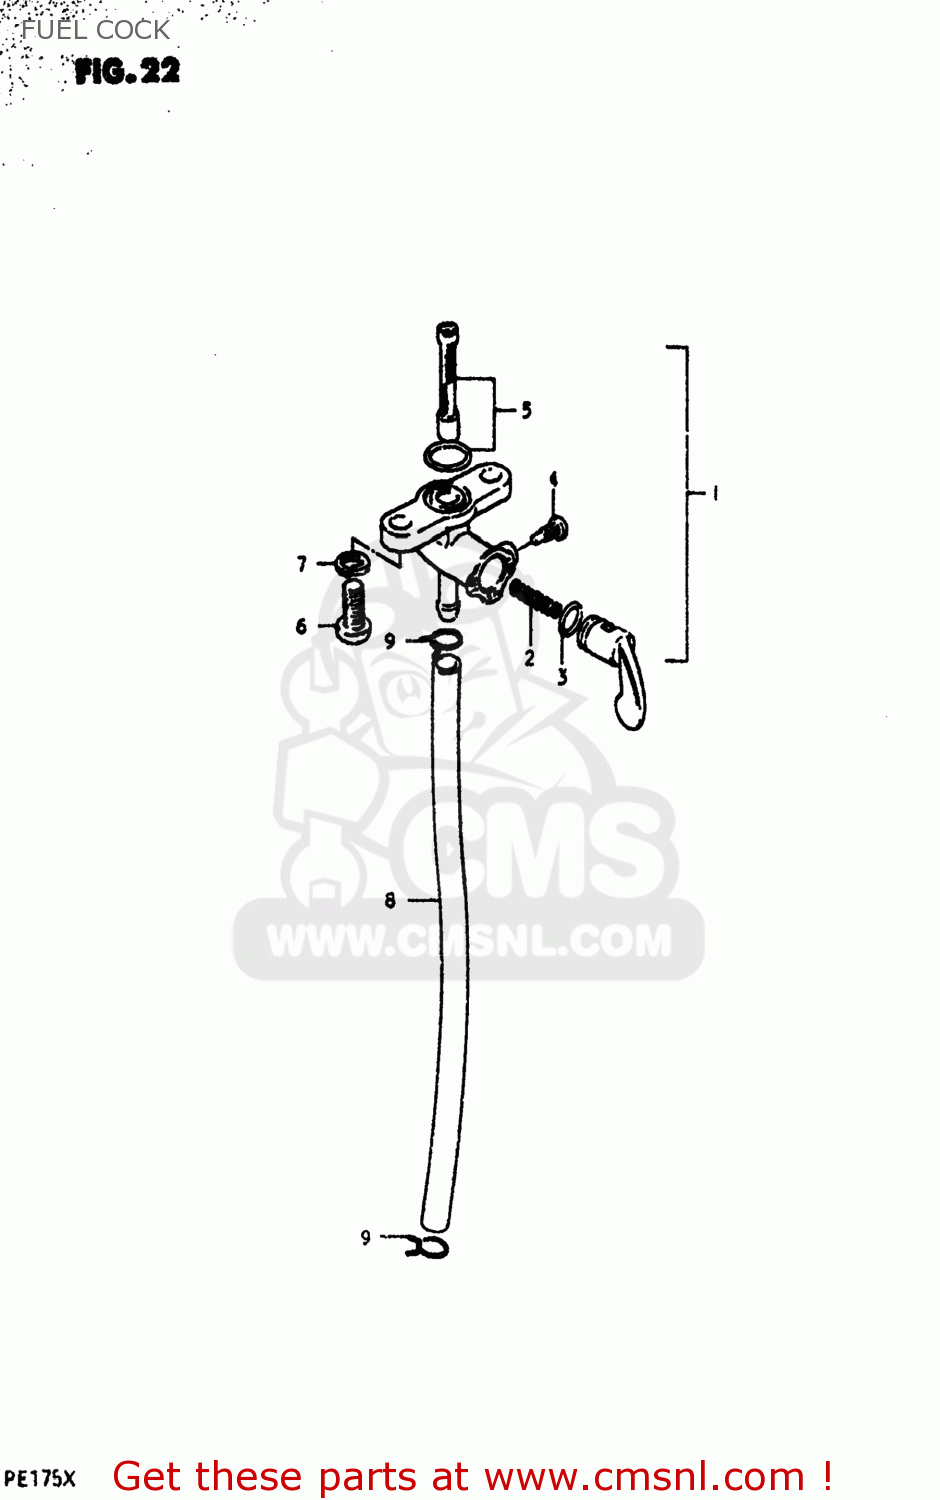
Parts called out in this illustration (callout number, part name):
1	COCK ASSEMBLY,FUEL
2	SPRING,FUEL COCK VALUE
3	O RING,LEVER
4	SCREW
5	FILTER SET FUEL
6	SCREW
7	LOCK WASHER
8	HOSE
9	CLAMP
